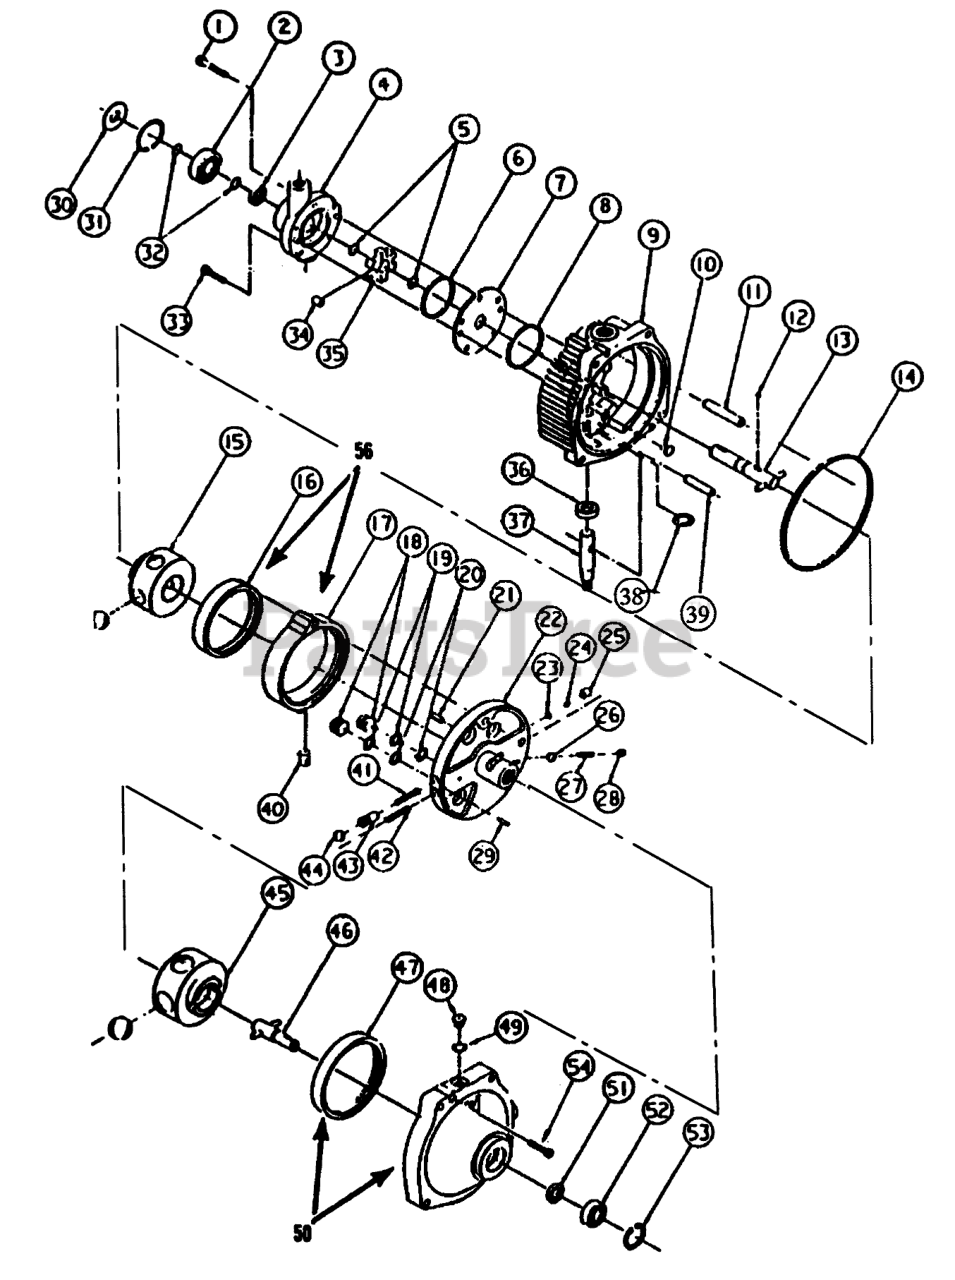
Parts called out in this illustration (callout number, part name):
1	Screw
2	Bearing-Input
3	Seal
4	PUMP-CHARGE
5	Ring
6	Ring-Seal
7	Plate
8	Ring-Seal
9	Cover Assembly (Incl.Ref. #3, 6, 8, 10, 11, 19, 20, 36-39, & 51)
10	Button
11	Pin-Pivot
12	Pin
13	Shaft-Input
14	Ring-Seal
15	Rotor-Pump
16	PUMP-RACE
17	Ring-Cam
18	Piston
19	Ring-Back Up
20	"O"Ring
21	Pin-Coil
22	Pintle Assembly (Incl. Ref. #21, 23-29 &41-44)
23	Ring-Retaining
24	Ball
25	Body-Check Valve
26	Ball
27	Spring-Relief Valve
28	Plug-Relief Valve
29	Pin
30	SHIELD-GRASS
31	RETAINING-RING
32	Ring
33	Screw
34	Roller
35	Carrier
36	Seal
37	Kit-Control
38	Washer
39	Dowel
40	Insert-Cam Ring
41	Spring-Acc. Valve
42	Spring-Acc. Valve
43	Body-Acc. Valve
44	Ball
45	Rotor-Motor
46	Shaft-Output
47	Race-Motor
48	Plug-"O"Ring (incl. Ref. #49)
49	O-Ring
50	Body Assembly (Incl. Ref. #51, 53 & 54)
51	Seal ASM
52	Bearing-Output
53	Retaining Ring
54	Screw
55	Kit-Seal, Overhaul (Incl. Ref. #3, 6, 8, 14, 19, 20, 36, 49 & 51)
56	Ring-Cam
